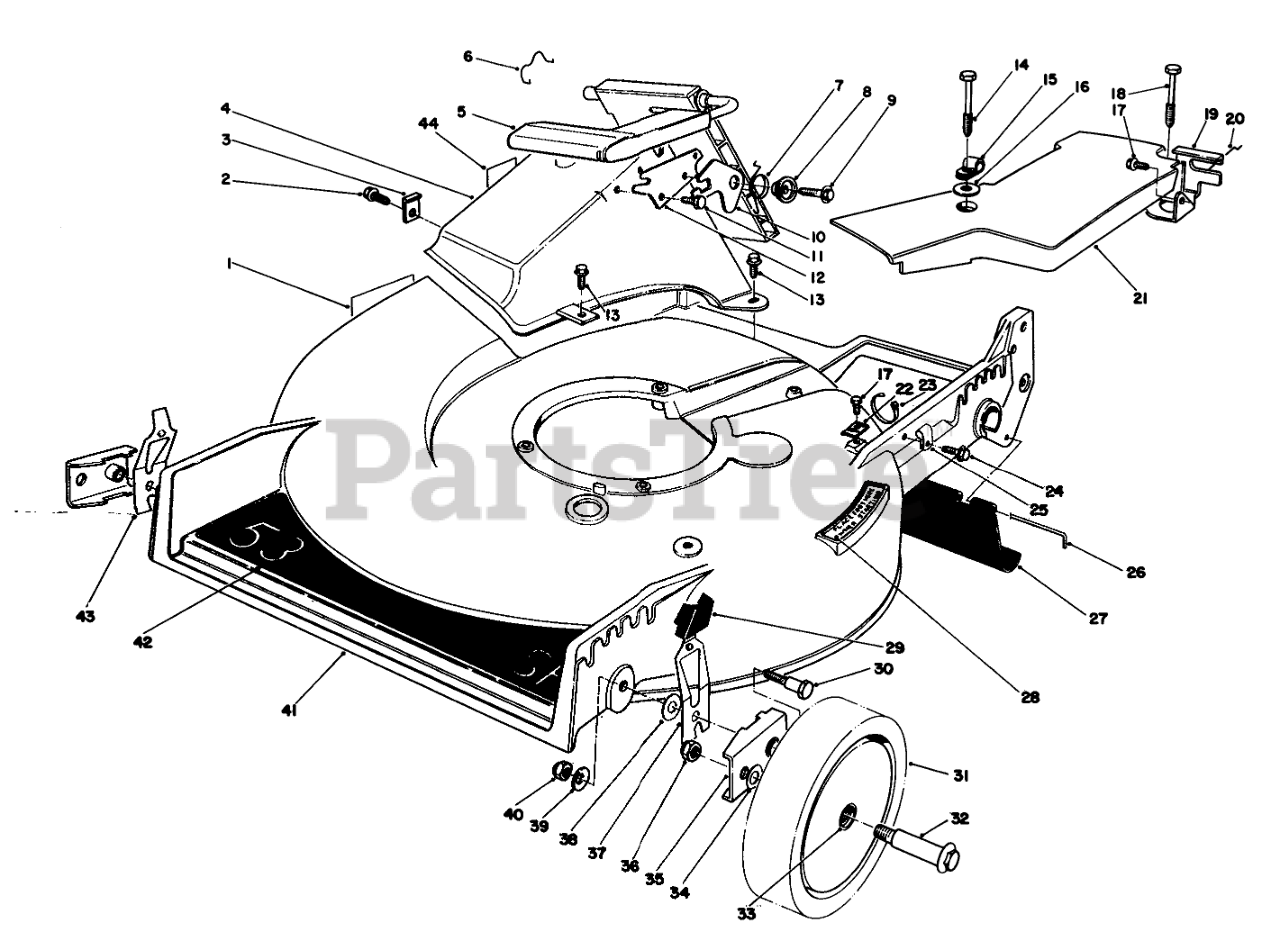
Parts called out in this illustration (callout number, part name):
1	Decal Danger
2	SCREW
3	TUNNEL CLIP
4	Tunnel Discharge
5	Discharge Door Assembly
6	DOOR RET SPRING
7	TORSION SPRING
8	DOOR SPACER
9	SCREW-HWH
10	SAFETY LATCH
11	SCREW-PLASTITE
12	DOOR LATCH PLATE
13	SCREW-HWH
14	SCREW-SPECIAL
15	CLAMP-CABLE
16	WASHER
17	SCREW-HWHTF
18	SCREW-HHFTF
19	Bracket-Traction Adj.
20	RETAINER-CABLE
21	Belt Cover
22	CLAMP-CABLE
23	TIE-CABLE
24	SCREW
25	CLAMP-CABLE
26	ROD-SHIELD
27	SHIELD-TRAILING
28	DECAL - STEP PAD INT'L
29	KNOB-ARM
30	PIVOT SCREW
31	Wheel & Tire Assembly (Incl. Ref. #33)
32	BOLT-WHEEL
33	BUSHING
34	WASHER
35	HP PIVOT ARM ASM
36	Nut
37	L. HP SPRING ARM ASM
38	WASHER-PIVOT
39	WASHER-BELLEVILLE
40	NUT-LOCK, NI
41	Housing (Incl. Ref. #1, 13 & 28)
42	Decal-53
43	R HP SPRING ARM ASM
44	DECAL - DANGER
